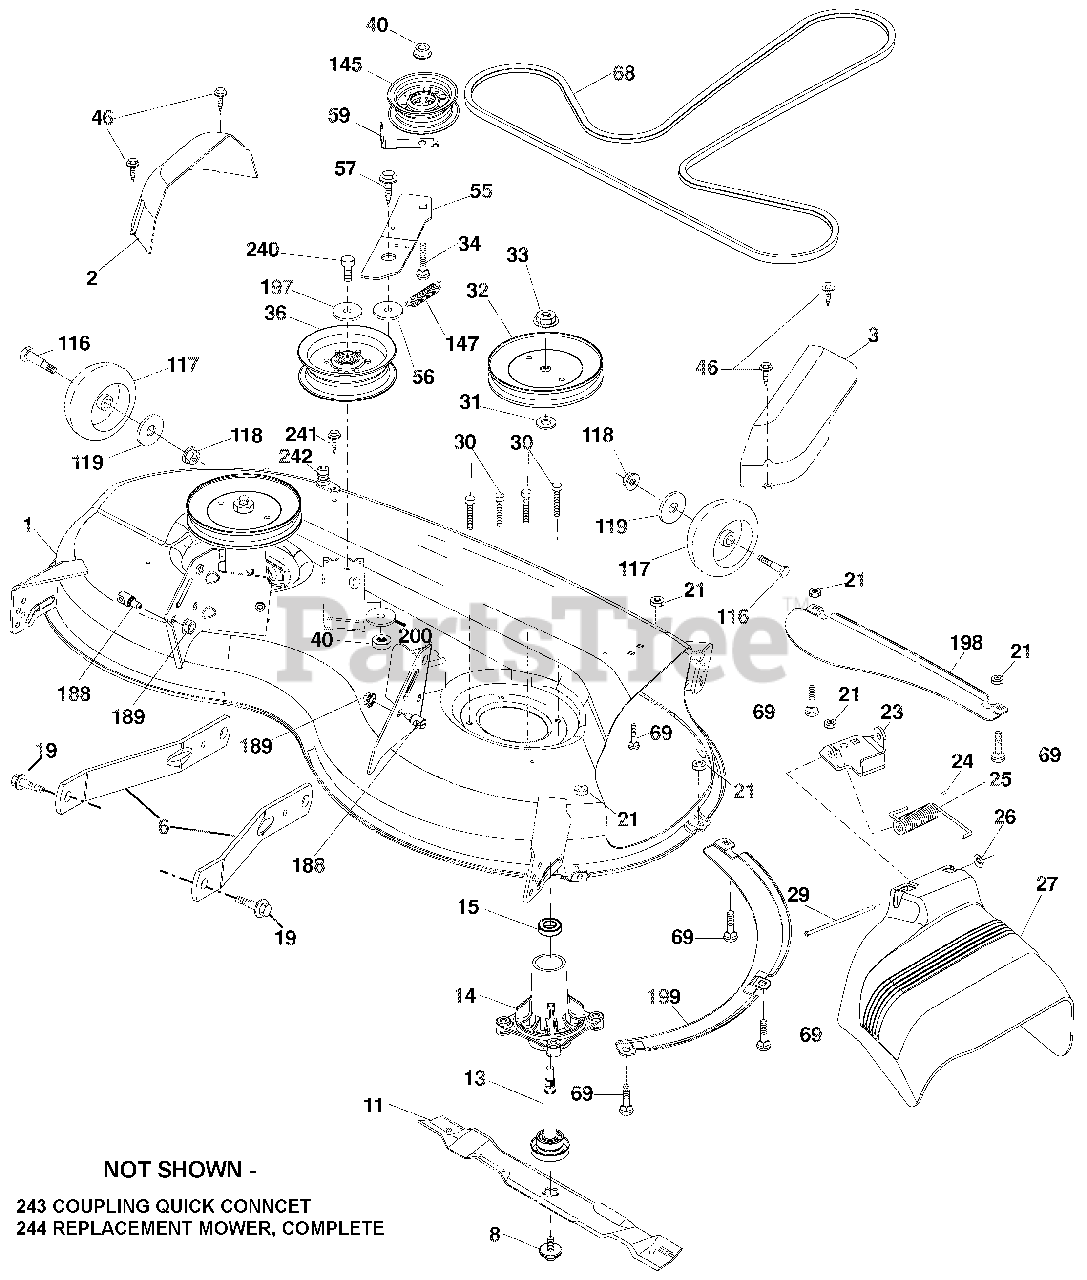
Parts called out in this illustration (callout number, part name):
1	MOWER HOUSING
2	COVER.MANDREL.LH.46"
3	COVER.MANDREL.RH.46"
6	ARM.SUSPENSION.MOWER.REAR.LD
8	BOLT/WASHER ASM.7/16-20.UNF
11	BLADE.MOWER.46"HI LIFT BAGGER
11	BLADE MOWER MULCHING
13	SHAFT ASM.MNDRL.N/GREASEABLE38
14	HOUSING.MANDREL.4PT.SERVICE
15	BEARING.BALL.MANDREL
19	BOLT.SHOULDER
21	Nut, Hex, Crownlock 5/16-18
23	BRACKET.DEFLECTOR.38/42"2005
24	CAP.SLEEVE..80X.112.BLK.MOWER
25	SPRING.TORSION.DFL.38/42/46.GR
26	NUT.PUSH.PHOS.& OIL
27	SHIELD.DEFLECTOR.MOWER 46"BLK
29	ROD.HINGE.42/46"
30	SCREW.THD ROLL.DOD PT.HEX
31	WASHER.SPACER.MANDREL
32	PULLEY.MANDREL.5.438 PD.42"
32	MANDREL ASM.SUB.N-GRS.4 BOLT
32	PULLEY/NUT/WASHER AND BLADE BOLT/WASHERS NOT INCLUDED)
33	NUT.FLANGE.LOCK.TOP
34	BOLT.CARR.SH.3/8-16X1-1/2.GR5
36	PULLEY.IDLER.4.50.RAW
40	Nut, Hex, Flangelock 3/8-16
46	SCREW.THD.ROLL.1/4-20 X 5/8
55	IDLER.ARM
56	SPACER.RETAINER
57	SCREW.3/8-16X1.SMGML.TAP/R.BLK
59	GUARD.TUV.IDLER
68	V-BELT.DRIVE.MWR.MECHANICL.46"
69	BOLT.5/16-18HEX.WHS.HD.LCKSERR
116	BOLT.SHLD."A"2.41."B"1.66
117	WHEEL.GAGE.HALF.SPOKED
118	Nut, Hex, Flangelock 3/8-16
119	Washer 3/8 x 7/8 x 14 Ga.
145	PULLEY.IDLER 48"PRIMARY
188	STUD.FASTNER.W/'D'ANTI-ROTATIO
189	Nut, Lock Hex Flange 5/16-18 u
197	Washer 13/32 x 13/16 x 12 Ga.
198	BAFFLE.CENTER.FRONT
199	BAFFLE.FRONT.RH
200	WASHER.13/32 X 1 X 1/2.11GAHRD
240	BOLT.FIN.HEX.3/8-16X 2-1/4 GR5
242	PORT WASHOUT
243	COUPLING QUICK CONNECT
244	REPLACEMENT MOWER, COMPLETE
